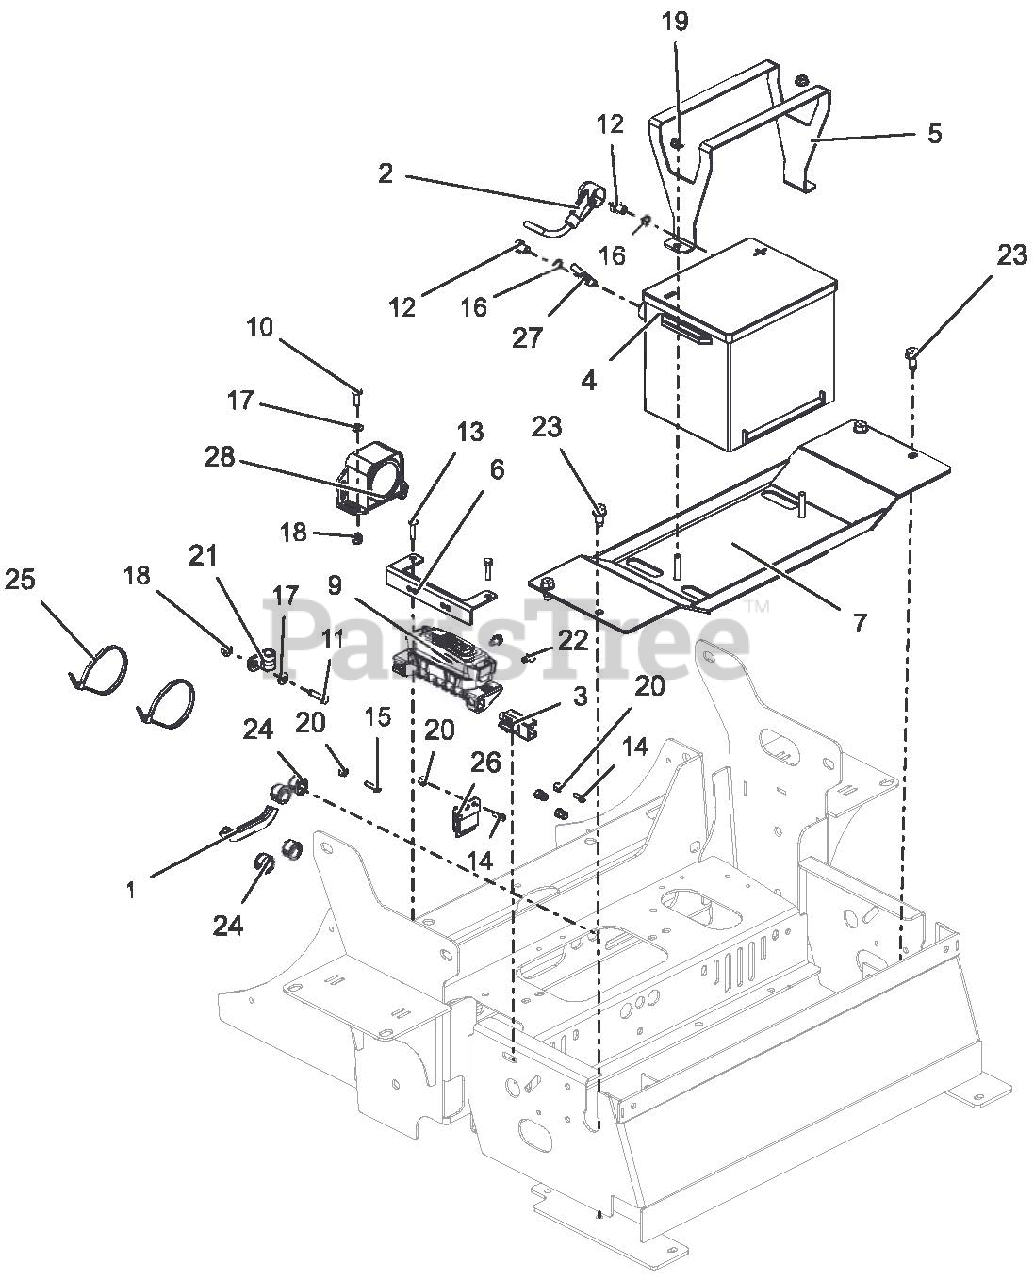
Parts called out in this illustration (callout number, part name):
1	STRIP, COWL - 1.50 LG
2	CABLE, POS BATT W/ BOOTS 6 X 35
3	SWITCH, SNAP IN - N.O./N.O
4	BATTERY, GROUP 70, 540 CCA
5	BRKT, BATTERY HOLD-DOWN
6	BRKT, FUSE HOLDER MOUNTING
7	WLDMT, PT400 DIESEL BATTERY TRAY
9	HARNESS, PT400 DIESEL WIRE
10	BLT-HEX .25-20 X .75 GR5 YWZC
11	BLT-HEX .25-20 X 1.00 GR5 YWZC
12	BLT-HEX .38-16 X .50 GR5 YWZC
13	@BLT-HEX M6-1.0 X 25 YWZC
14	@SCR-MCH 10-24X.50 HWH YWZC
15	@SCR-MCH 10-24X.75 HWH YWZC
16	LOCK, WSHR-EXT 0.391 X 0.628 X 0.036 YWZC
17	WSHR-FL-STL .281 X .62 X .065 YWZC
18	NUT-LK-NYL-FLG .25-20 YWZC
19	@NUT-SPNLK-FLG .312-18 YWZC
20	NUT-LK-NYL #10-24 YWZC
21	CLAMP, CUSHIONED STEEL
22	SCR-TAP .25-20X.50 HWH TR YWZ
23	SCR-TAP .25-20X.75 HWH TR YWZ
24	BUSH, PANEL SNAP .687 X .875 X .56
25	CABLE, TIE 5.50 LG
26	NODULE, INTERLOCK
27	CABLE, NEGATIVE BATTERY .385 X 49.00
28	ALARM, BACKUP
